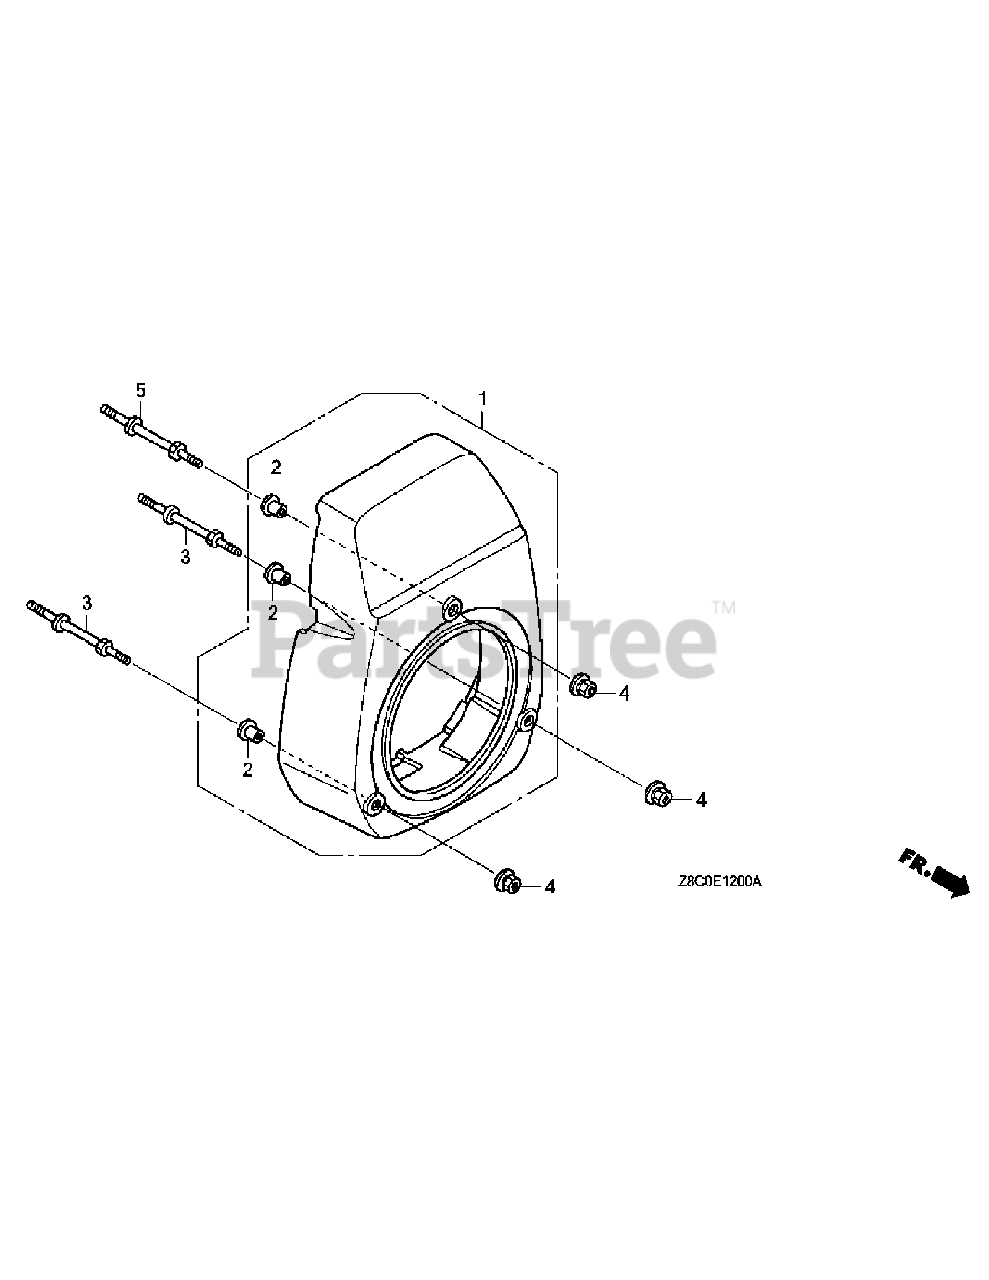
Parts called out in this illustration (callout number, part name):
1	Cover, Fan *Nh1 *
2	Collar, Fan Cover
3	Bolt, Stud (H=42.5Mm)
4	Nut, Flange, 6Mm
5	Bolt, Stud (H=42.5Mm)
